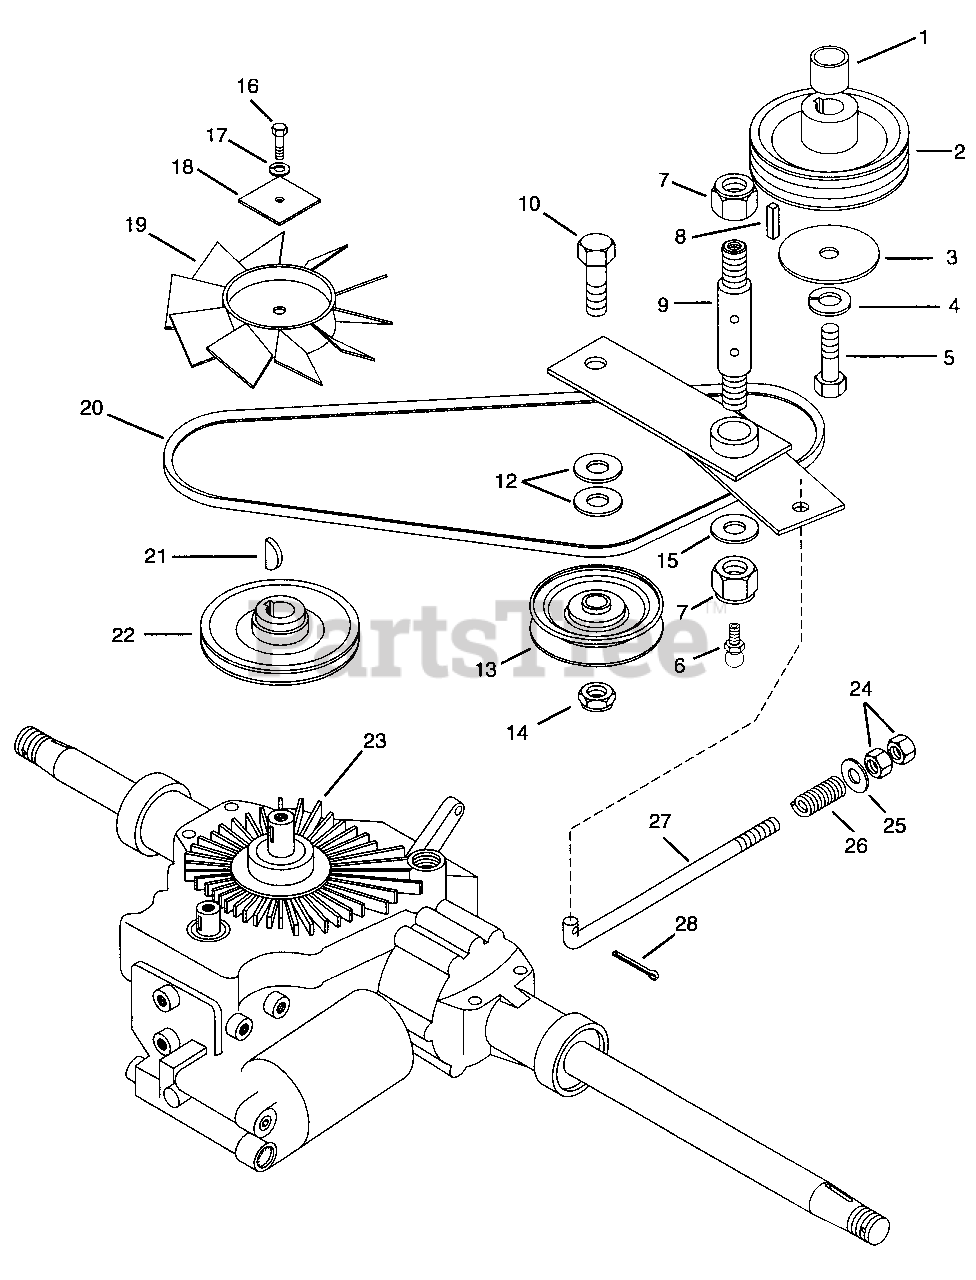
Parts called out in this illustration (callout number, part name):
1	Bushing, Sleeve 1.13 x 1.38 x 1.25
2	Sheave
3	Washer-Special .469 x 2.000 x .250
4	Washer-Locking .44 x 109
5	Bolt-Hex .44-20 x 1.50
6	Fitting, Lube 1/8
7	Nut-Locking-Center .62-11
8	Key-Square .248 x 1.25 x .248
9	Pin, Pivot
10	Bolt-Hex .38-16 x .50 Grade 5
11	Weldment, Idler Arm
12	Washer-Flat-Steel .531 x 1.06 x .095
13	Pulley-V 4.00 x .84
14	Nut-Locking- Center .50-13
15	Washer-Flat-Steel .656 x 1.31 x .095
16	Bolt-Hex .25-20 x 1.25 Grade 5
17	Washer-Lock .25 x .062
18	Washer-Flat-Steel .265 x 1.75 Square x .119
19	Fan
20	V-Belt A-Section 18.05 x .495
21	Key, Woodruff .19 x .63
22	Pulley, Drive
23	Transaxle, Eaton #851-109
24	Nut-Hex .375-16
25	Washer-Flat-Steel .406 x .812 x .065
26	Spring-Compression .072 x .561 x 2.50
27	Rod, Idler
28	Pin-Center .09 x .75
